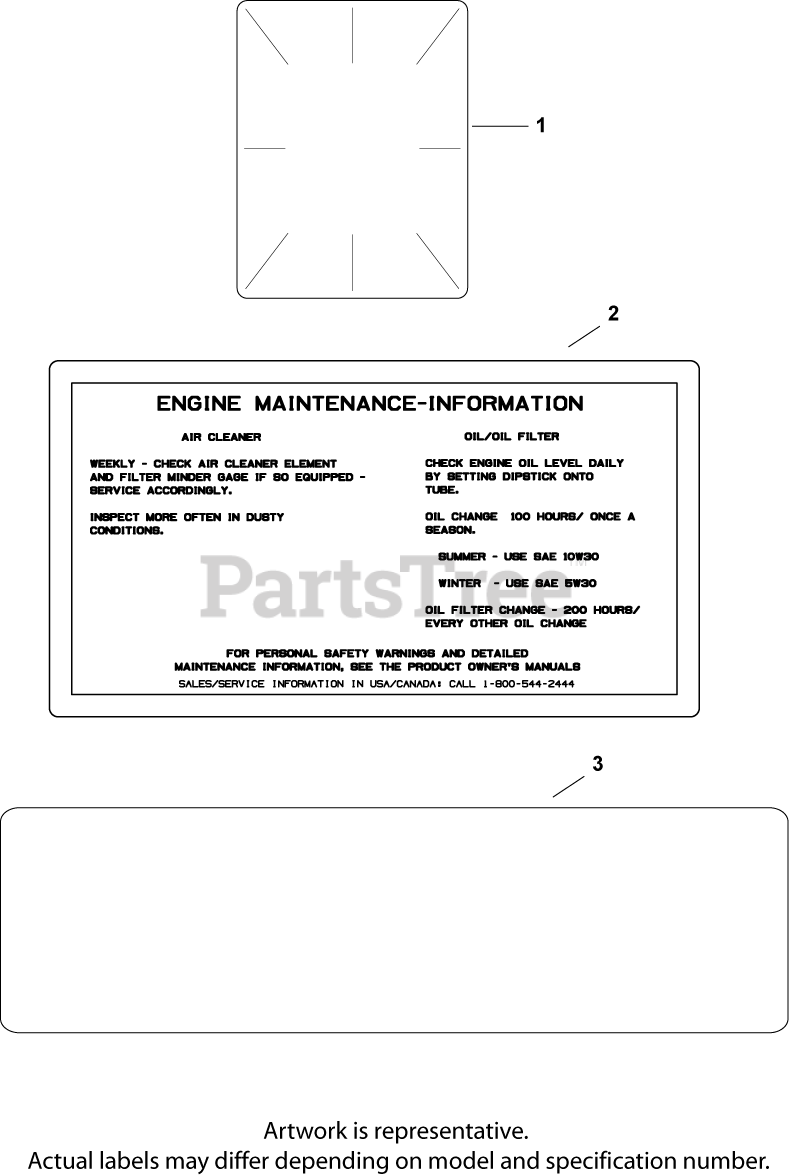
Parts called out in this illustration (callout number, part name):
1	DECAL, CLEAR LAMINATE USE 25 113 70-S
2	DECAL, AIR CLEANER - (#DSC)
3	DECAL, 20 HP
